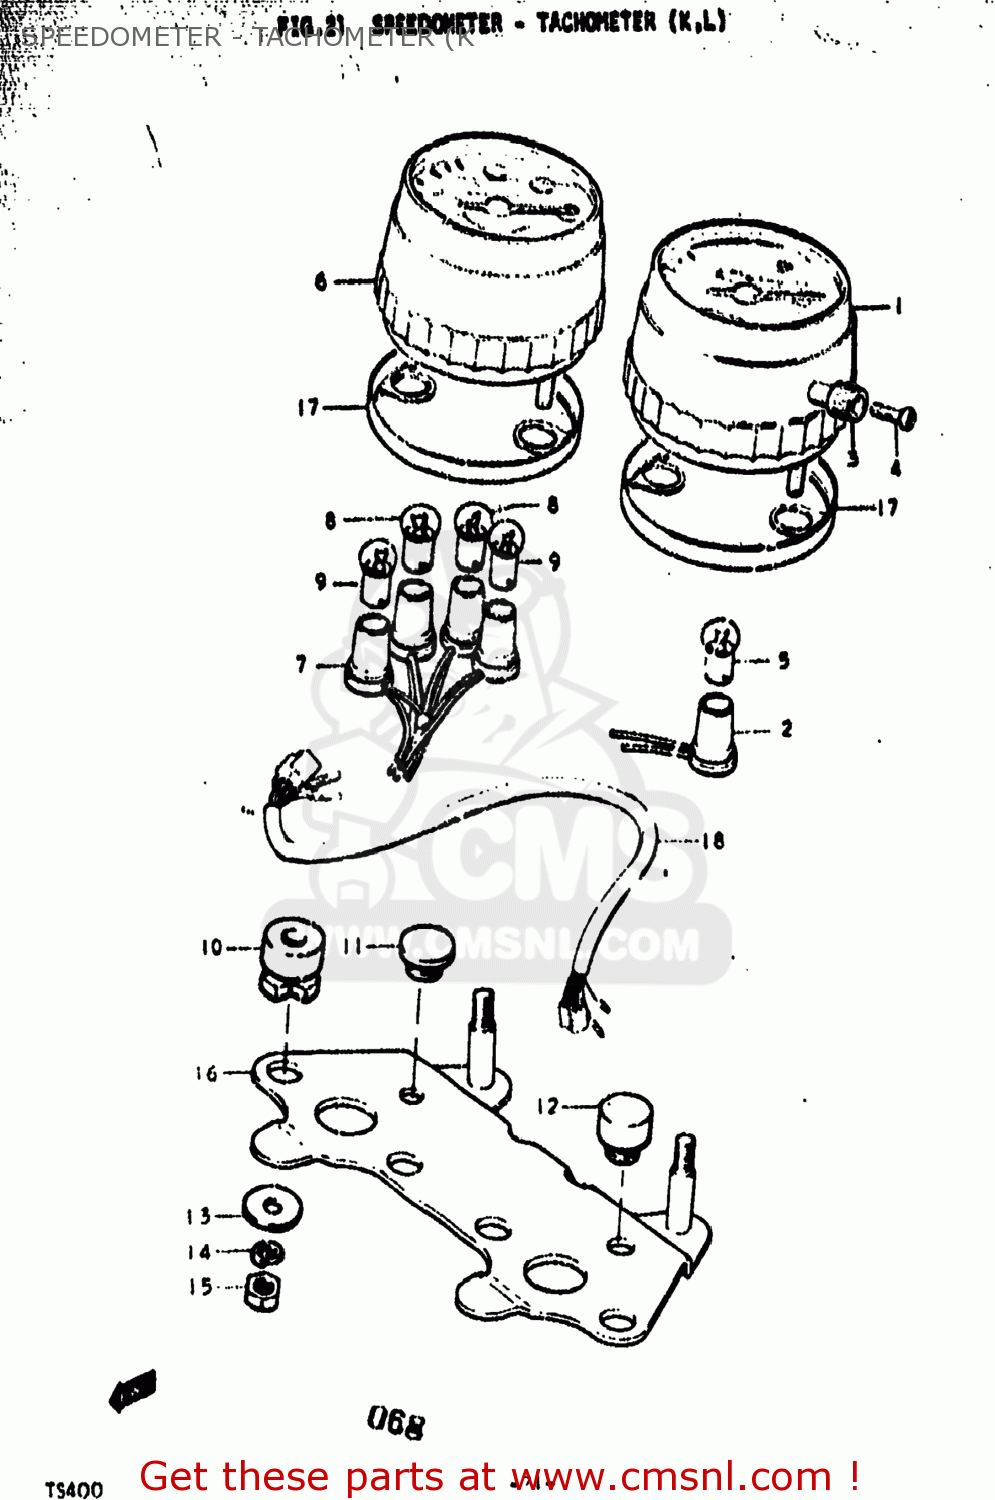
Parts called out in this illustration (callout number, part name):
1	SPEEDOMETER ASSEMBLY
2	SOCKET,METER
3	KNOB, TRIP METER
4	ROTOR,SPEED
5	BULB(12V3.4W,STANLEY,A72A)
6	METER,TACHOMETER
7	SOCKET,METER
8	BULB(12V1.7W,A71A)
9	BULB(12V3.4W,STANLEY,A72A)
10	CUSHION,METER NO.1
11	CUSHION,METER
12	CUSHION,METER
13	WASHER
14	LOCK WASHER
15	NUT
16	BRACKET,METER
17	BRACKET,SPEEDOMETER
